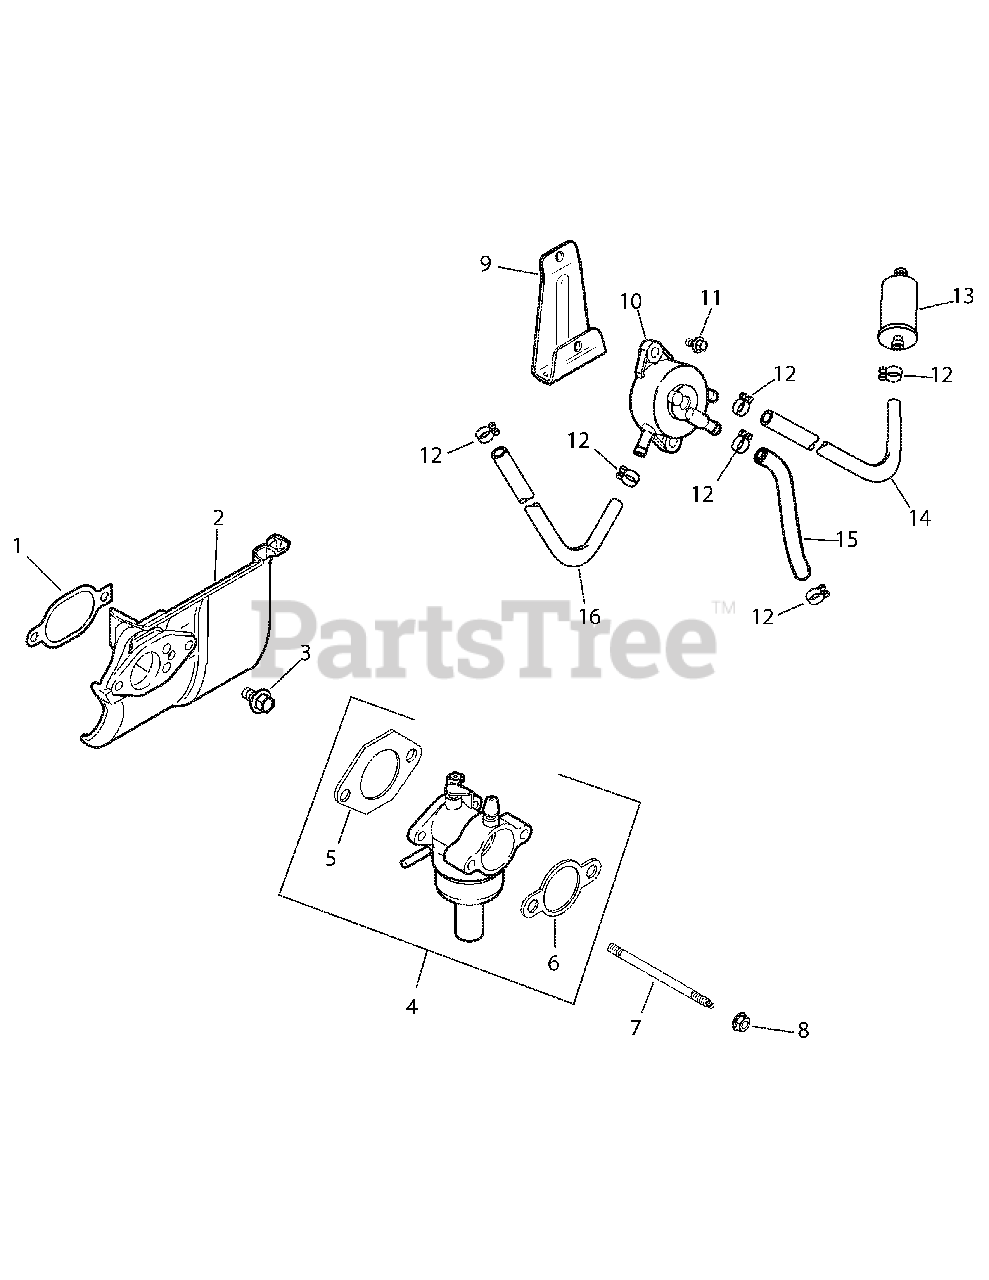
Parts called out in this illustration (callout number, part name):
1	Gasket, Heat Deflector
2	Deflector, heat
3	Screw, hex. flange
4	Carburetor w/Gaskets (includes 5,6)
5	Gasket, Carburetor
6	Gasket, Air Cleaner
7	Stud, Carb Mounting
8	Nut, Hex Flange M6x1.0
9	Bracket, Fuel Pump Mounting
11	Screw, hex. Flange
12	Clamp, hose
13	Filter, Fuel
14	Line, fuel 15.75" (pump to filter)
15	Line, fuel 2" (pump to carburetor)
16	Line, fuel 10" (pump to fitting)
